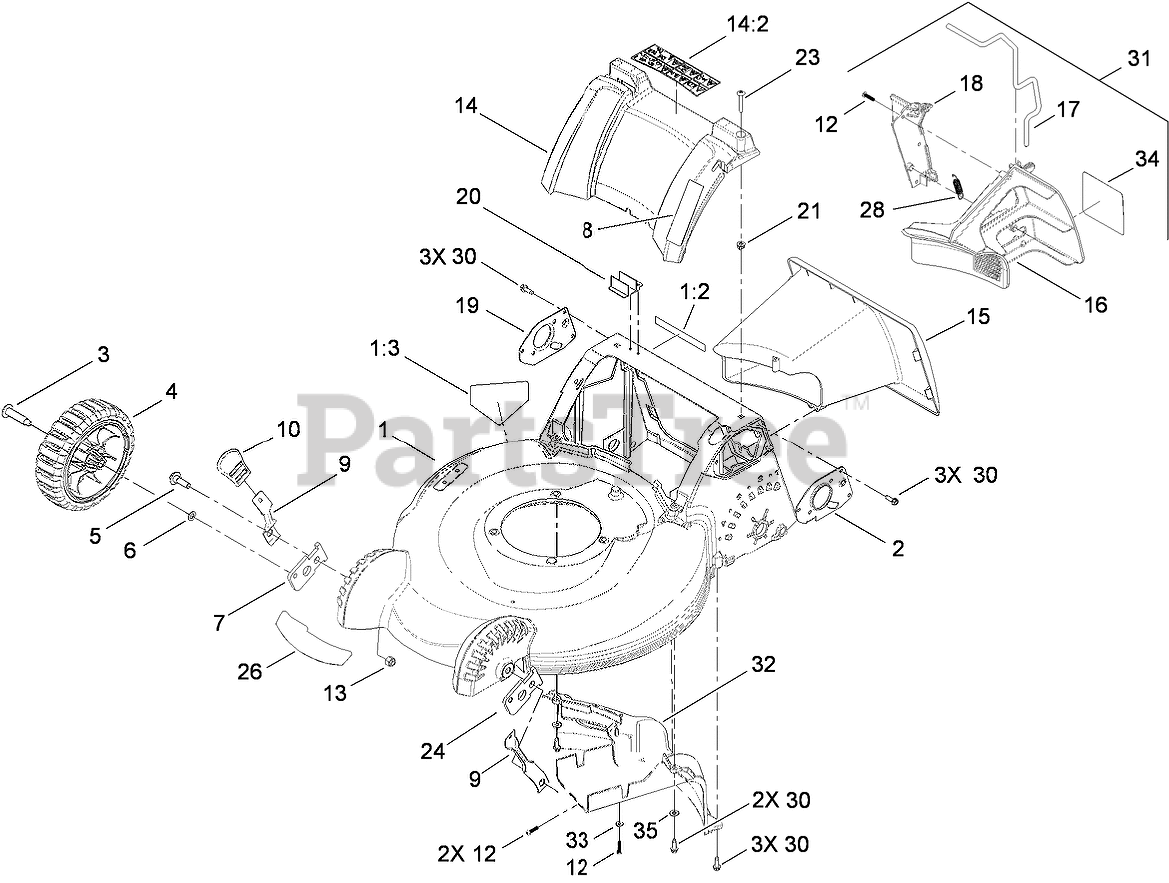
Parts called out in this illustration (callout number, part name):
1	HOUSING ASM
1:2	DECAL-SAFETY
1:3	DECAL-DANGER
2	MOUNT-HANDLE, LH
3	BOLT-SHOULDER
4	8 INCH WHEEL ASM
5	BOLT-SHOULDER
6	WASHER
7	ARM-PIVOT, RH
8	DECAL-QUICK STOW
9	ARM-SPRING, FRONT
10	KNOB-HOC
12	SCREW-PLASTITE
13	NUT-LOCK, NI
14	REAR COVER ASM
14:2	DECAL-WARNING
15	TUNNEL
16	PLUG-MULCH, LH
17	LATCH-PLUG, MULCH
18	PLUG-MULCH, RH
19	MOUNT-HANDLE, RH
20	MODULE-SWITCH
21	NUT-CLIP
23	SCREW-PTH
24	ARM-PIVOT, LH
26	DECAL-SUPER BAGGER
28	SPRING-EXTENSION
30	SCREW-HWHTF
31	MULCH PLUG ASM
32	BAFFLE-REAR
33	WASHER-FLAT
34	DECAL-PLUG, MULCH
35	WASHER-FLAT
